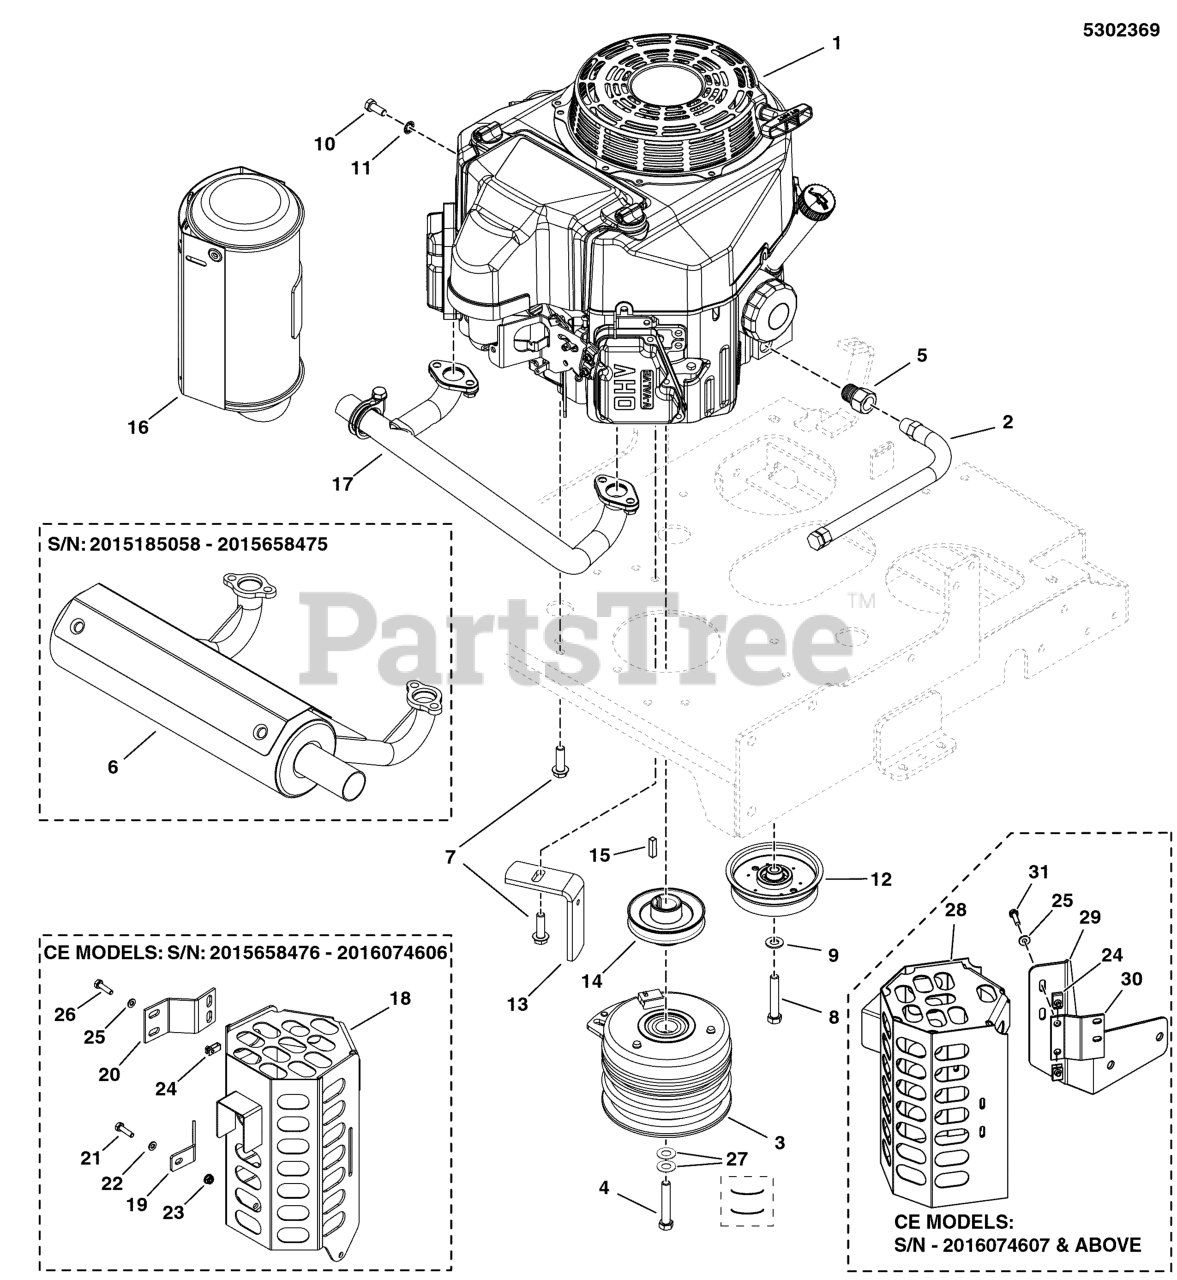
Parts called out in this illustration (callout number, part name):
2	HOSE, OIL DRAIN
3	CLUTCH, WARNER, 125 ft lbs - 1"
4	BOLT, CRANKSHAFT, 7/16-20 X 3, GD8
5	ADAPTER-OIL DRAIN
6	MUFFLER, KAWASAKI, HORIZONTAL
7	BOLT,HEX FLG,SER GD5 3/8-16X1-1/4PACH CZ
8	BOLT, 3/8-16 X 2 GD5 TFL
9	WASHER, 3/8 SAE
10	BOLT, M8-1.25 X 20MM GD8.8
11	WASHER, 5/16 INT. TOOTH LOCK
12	PULLEY, IDLER, SINGLE FLANGE, 4" OD
13	ANCHOR, CLUTCH, SINGLE HOLE - RED
14	PULLEY, CRANKSHAFT, 1.0005 ID X 4.25 OD
15	KEY, 1/4 SQ X 1
16	* MUFFLER
17	* MANIFOLD
18	WELD, MUFFLER GUARD, CCW - RED
19	BRACKET, MUFFLER GUARD - RED
20	BRACKET, GUARD MOUNT - RED
21	BOLT, 5/16-18 X 1 GD5 YZ
22	WASHER, 5/16" SAE
23	NUT, 5/16-18 HEX NYLOCK FLANGE
24	BODY CLIP, 1/4-20 X 1/2 DEEP
25	WASHER, 1/4 SAE
26	BOLT, 1/4-20 X 3/4 GD5 YZ
27	BELLEVILLE WASHER 1.1875 X .442 X .089
28	WELD, MUFFLER GUARD
29	GUARD, MOUNT
30	GUARD, MOUNT
31	BOLT, 1/4-20 X 1" GD5 CZ
